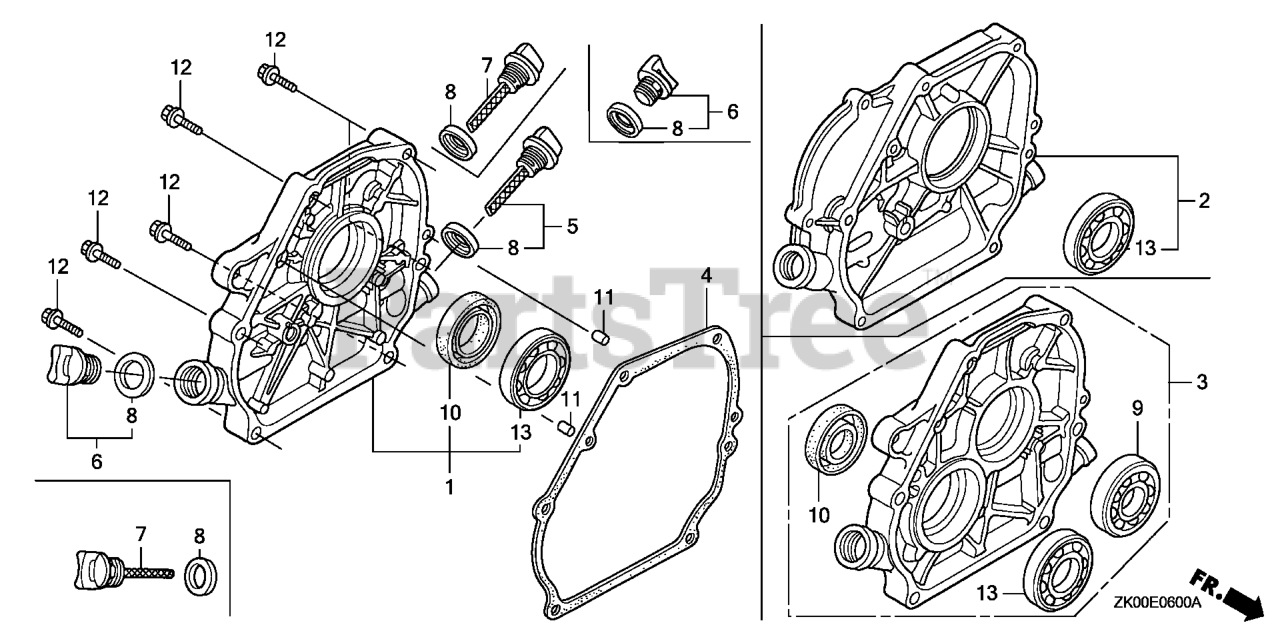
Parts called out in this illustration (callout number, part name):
1	COVER ASSY., CRANKCASE
4	GASKET, CASE COVER
5	CAP ASSY., OIL FILLER
6	CAP ASSY., OIL FILLER
8	GASKET, OIL FILLER CAP
10	OIL SEAL (25X41X6)
11	PIN A, DOWEL (8X14)
12	BOLT, FLANGE (8X32)
13	BEARING, RADIAL BALL (6205)
